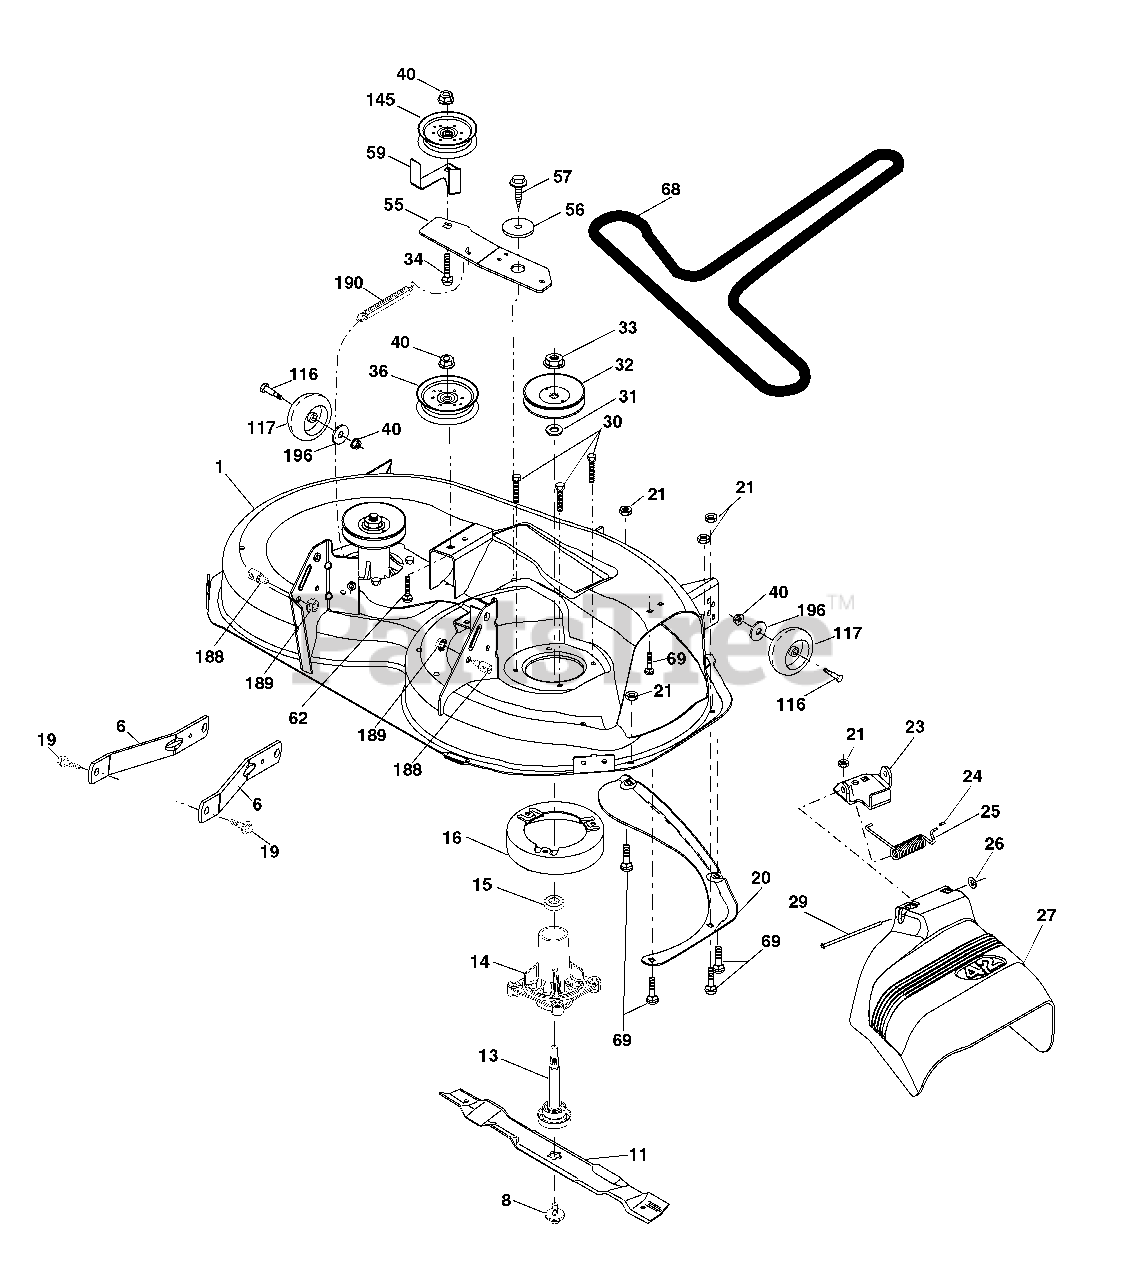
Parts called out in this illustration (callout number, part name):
1	Mower Housing
6	Arm Suspension
8	Bolt/Washer asm 7/16-20 unf
11	Blade, 42" Hi-Lift
11	Blade, 42" Mulching Std
11	Blade, 42" Mulching Premium
13	Shaft Assembly, Mandrel
14	Housing, Mandrel
15	Bearing, Ball, Mandrel
16	Stripper, Mower Deck
19	Bolt, Shoulder
20	Baffl e, Vortex
21	Nut, Crownlock 5/16-18 unc
23	Bracket, Defl ector
24	Cap, Sleeve
25	Spring, Torsion, Defl ector
27	Shield, Defl ector
29	Rod, Hinge
30	Screw Thdrol Rolling Wsh Hd
31	Washer, Spacer
32	Pulley, Mandrel
33	Nut, Toplock, Flanged
34	Bolt Carr Sh. 3/8-16 x 1-1/2 Gr. 5
36	Pulley, Idler, Flat
40	Nut, Lock Flg. 3/8-16 unc
55	Arm, Idler
56	Spacer, Retainer
57	Screw 3/8-16 x 1
59	Guard, Tuv Idler
62	Bolt Rd Hd Sq Nk 3/8-16 unc x 2
69	Bolt
116	Bolt, Shoulder
117	Wheel, Gauge
145	Pulley Idler
188	Stud Fastener
189	Nut Lock Hex Flange
190	Spring Mower Drive
196	Washer 13/32 x 1-1/4 x 12 Ga.
196	Mandrel Assembly
196	Replacement Mower, Complete
